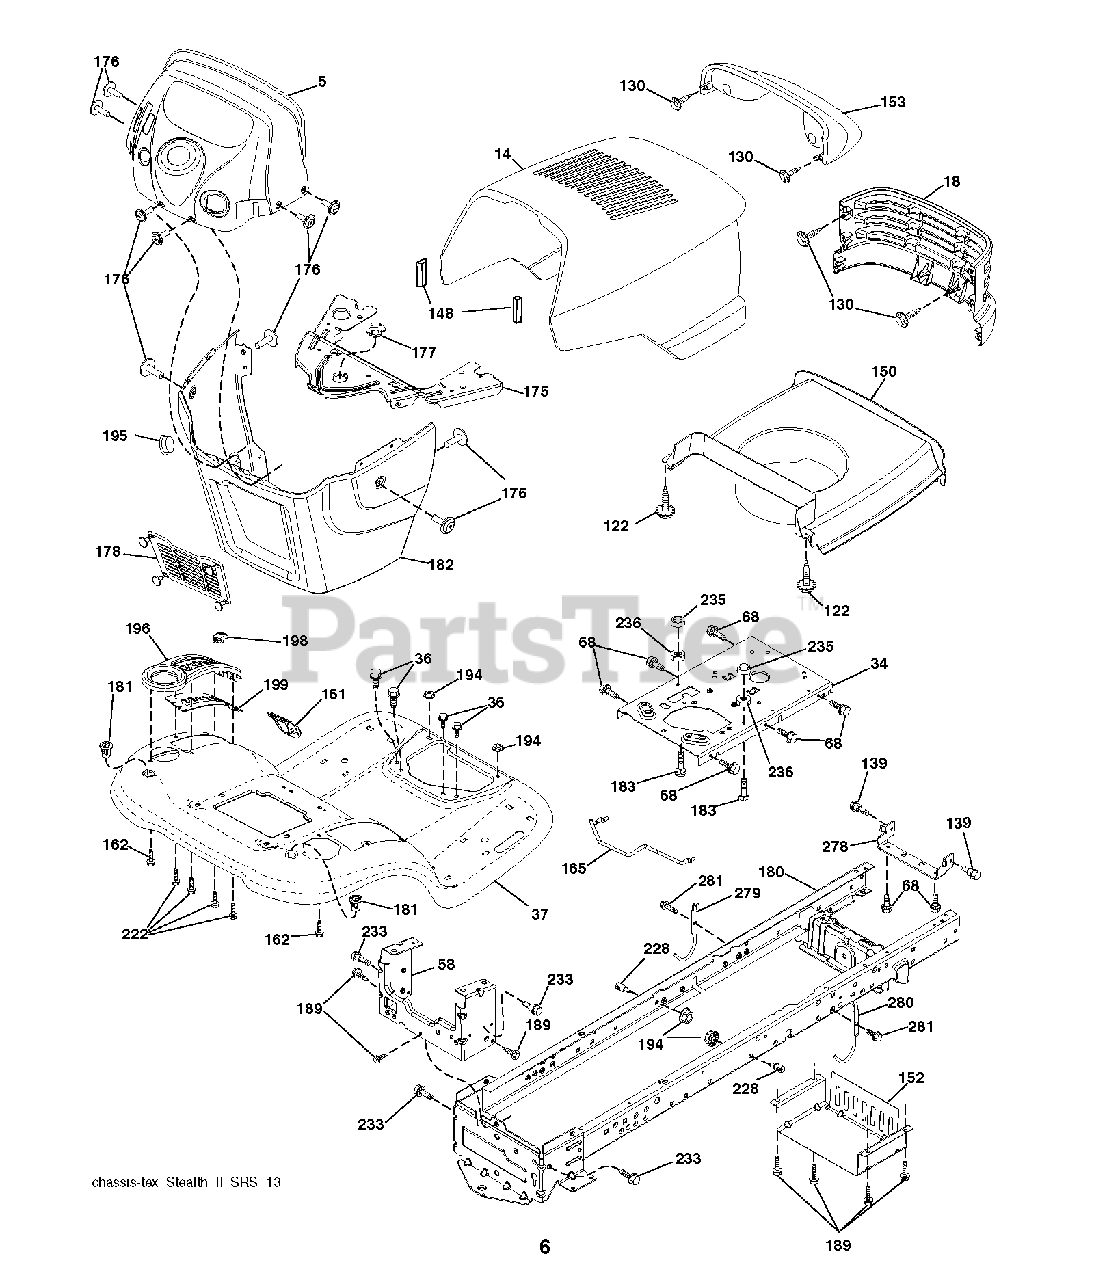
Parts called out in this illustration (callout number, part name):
5	DASH.UPR.STEALTH
34	PLATE.ENGINE.WELDED.CHASSIS
36	SCREW 5/16"
58	DRAWBAR.UPPER.2PC,LRG.FENDER
99	ROD ASM BYPASS
122	SCREW.WSHD.HEX10-32X5/8
130	SCREW
139	BOLT, SHOULDER 5/16-18
148	EXTRUSION BUMPER
150	DUCT HOOD
152	SHIELD BROWNING
161	CONSOLE.FUEL.WINDOW.STGT.BLACK
162	SCREW.HI-LO.CONSOLE
165	SUPPORT.TANK.REAR.W/TE
175	CROSSMEMBER.
176	SCREW.#10-24X5/8.RN.QU
177	BUSHING,STEERING
178	CARGO.ASM.NET.DASH.LOWER
180	CHASS.WLDMNT.TL.12GA/2P.48/54
181	FEND/FTRST.PCH.CPH.NFW
182	DASH.LOWER.
183	BOLT.5/16-18X1-1/4 FULL.THREAD
189	SCREW
194	NUT LOCK HEX FLANGE 5/16-18
195	PLUG.HOLE.DASH.LOWER.12V.BLK
198	INDICATOR DECK LIFT
199	PLATE DECK LIFT
222	SCREW.1/4-20X5/8
228	STUD.FASTNER.W/ANTI-ROTATE
235	SPACER FENDER
236	NUT.CENTERLOCK.5/16-
278	BRKT.HOOD/MUFF.STEALTH
